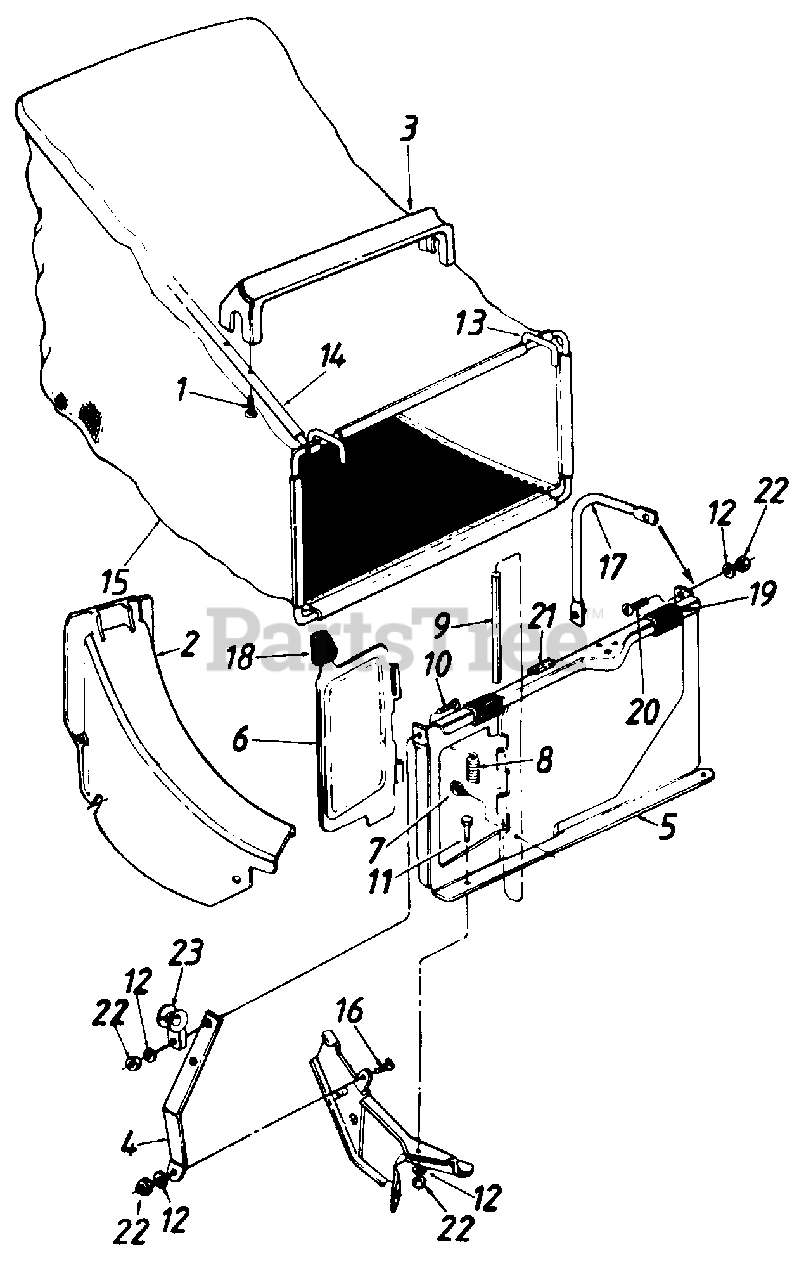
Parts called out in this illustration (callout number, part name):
1	Hex AB-Tap Scr. #12 x 1.25" Lg
2	Rear Discharge Chute Ass'y.
3	Bag Handle
7	Hex B-Tap Scr. #10 x .38"
8	Torsion Spring
9	Pivot Pin
10	Truss Mach. Scr. 1/4-20 x 3/4" Lg.
11	Hex Bolt 1/4-20 x .50" Lg.
12	L-Wash. 1/4" I.D.
15	21" Rear Discharge Grass Bag
16	Hex Bolt 1/4-20 x .62" Lg.
17	Catcher Panel Support Arrn
18	Door Grip
19	Panel Clip
20	Truss Mach. Scr. 1/4-20 x .62" Lg.
21	Foam Strip
22	Hex Nut 1/4-20 Thd.
23	Rope Guide
